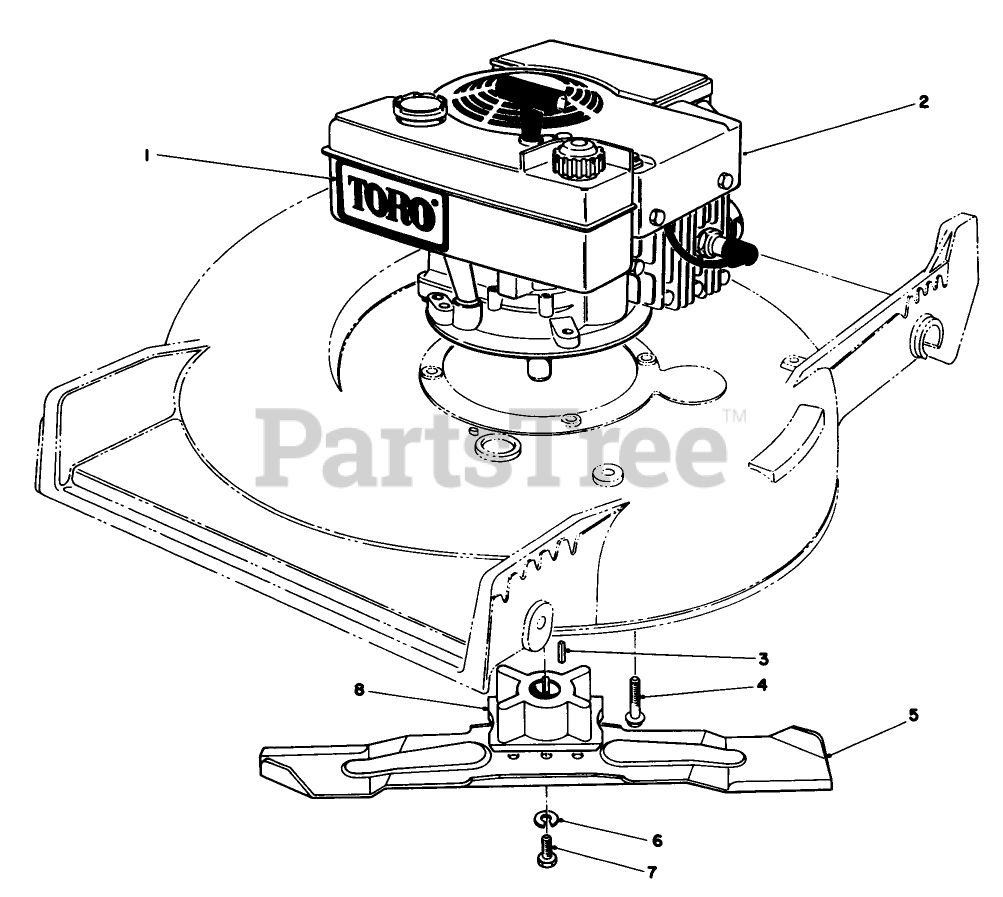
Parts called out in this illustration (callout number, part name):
1	Decal Tow
2	Engine
3	KEY-SQUARE
4	3/8-16 X 2 CAPSCREW
5	BLADE-21in
6	WASHER-LOCK
7	SCREW-BLADE
8	BLADE RETAINER(DEEP)
